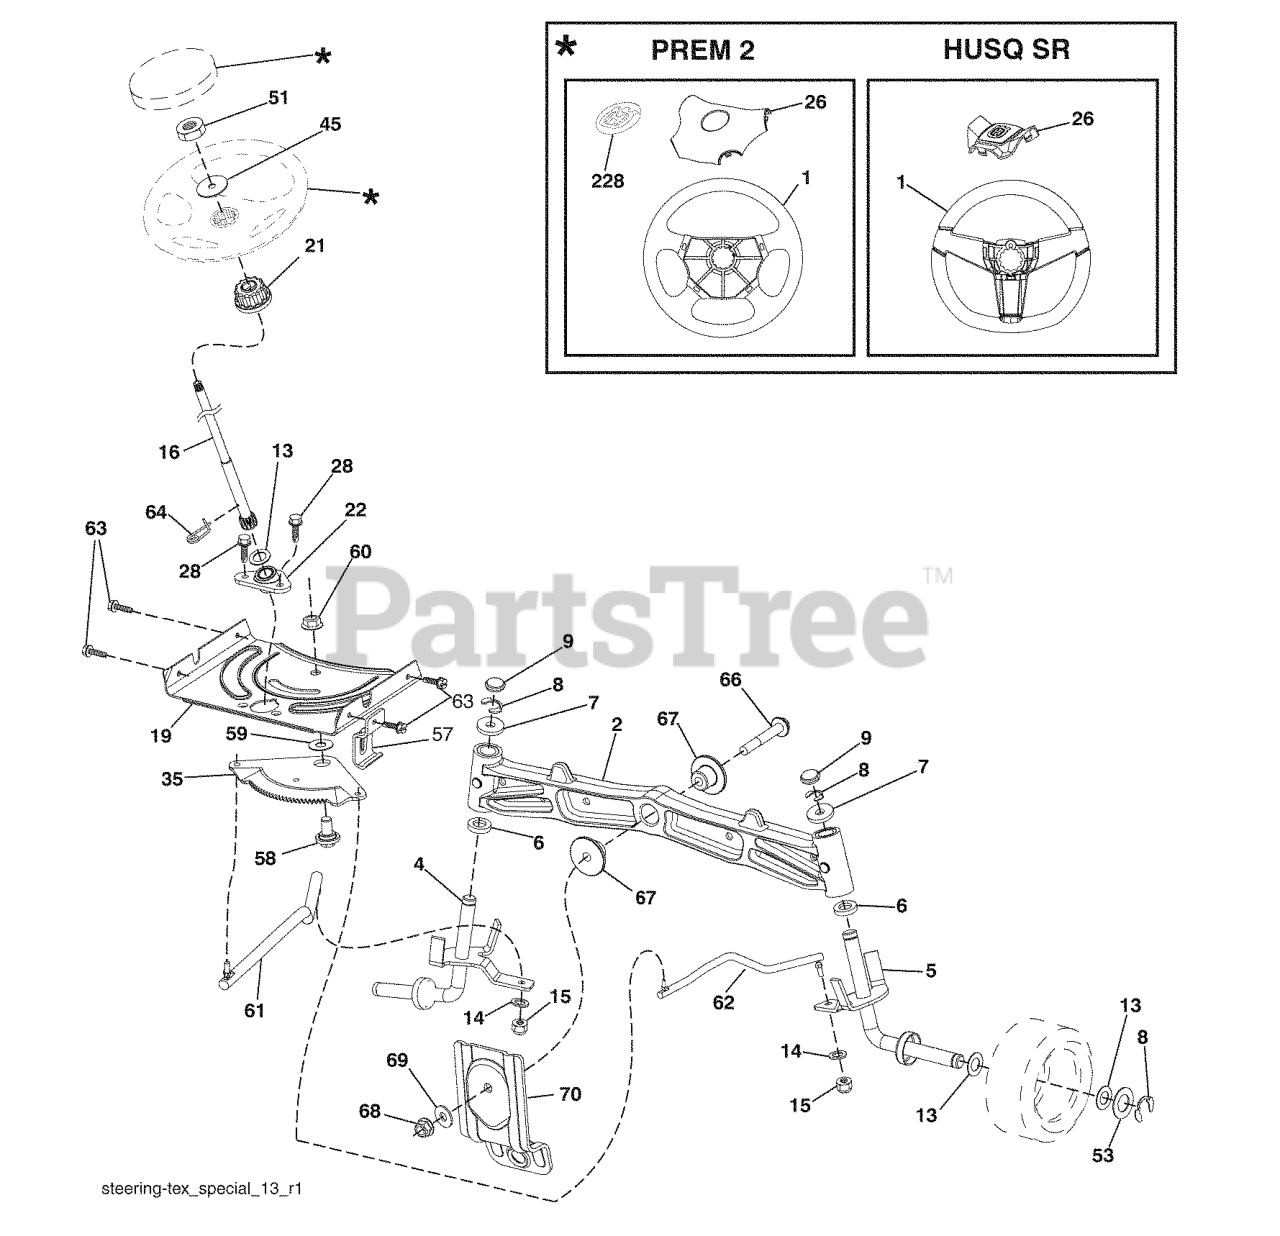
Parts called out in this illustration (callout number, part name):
1	RP WHEEL.STEER.HUSQ.PREM.OVMLD
2	AXLE.CAST.IRON
4	SPINDLE.WELDED.LH.15"TEX
5	SPINDLE.WELDED.RH.15"T
6	THRUST WASHER
9	CAP.SPINDLE.BLACK
14	WASHER, LOCK 3/8
15	NUT CROWNLOCK 3/8-24
16	SHAFT, STEERING
19	PLATE.STEER.DDL.NLT/NG
21	ADAPTER, WHEEL STNG..
22	BUSHING.ASM.STEERING.A
26	RP INSERT.CAP.WHL.STRG.HUSQ.
28	SCREW, 3/8-16X3/4
35	GEAR.SECTOR.PLATE.DDL.
45	WASHER 9/16"ID, 2 3/8"OD
51	NUT.HEX.1/2-20
53	WASHER.HARDENED
57	BRKT.UPSTOP.GT/LT.TEX
58	BOLT.SHOULDER.SECTOR.P
59	WASHER.THURST.SECTOR.S
60	NUT FLANGE LOCK 5/8-11
61	DRAGLINK.LH.BALLSTUD.D
62	DRAGLINK.RH.BALLSTUD.D
63	SCREW
64	RETAINER.CLIP.SPRING.S
66	BOLT HEX FGHD 7/16-14 X 3 SERR
67	BUSHING.PM.FRONT AXLE
68	NUT.LOCK.FLANGE.7/16
69	WASHER.1.5X.505X.118
70	BRKT.DECK.SUSPENSION.F
228	DECAL.WHEEL.STRG.LGN.H
